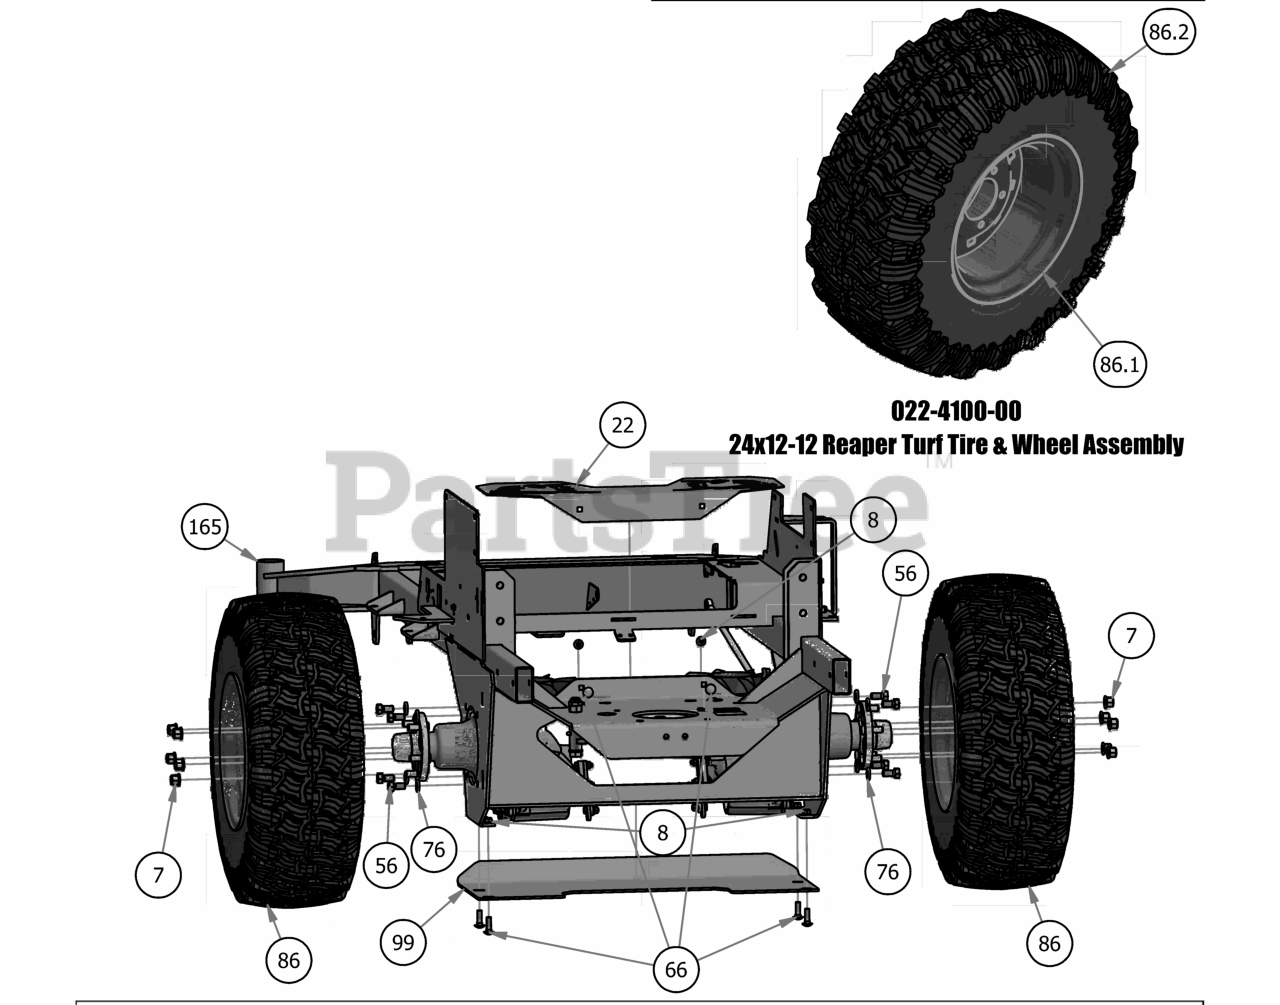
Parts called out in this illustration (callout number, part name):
7	Acorn Lug Nut
8	3/8" Nylock Flange Nut
10	3/8-16 Hex Nuts Zinc
12	1/2" Hex Nut
15	5/16" Nylon Flange Nut
22	2019 Rigid Fan Guard
50	All Thread-Pump Idler Tensioner
51	5/16 x 1 1/4 Hex Bolt
52	5/16" x 1" Bolt
56	1/2" x 1" Hex Bolt
61	1/2" Nylcock Nut (1/2 Jam)
65	3/8" x 1 1/4" Hex Bolt
66	3/8" x 1 1/4" Carriage Bolt
76	1/2" Lock Washer Zinc
77	3/8" Lock Washer
86	24x12-12 Reaper Turf Tire & Wheel Assembly
86.1	12x12" Black Wheel For 2015 Outlaw
86.2	24x12-12 Reaper Turf Tire
99	2019 Outlaw Rigid Skid Plate
125	Deck spring big diameter
126	2019 Outlaw Rigid Push Rod Assembly
127	2015 Outlaw Brake Adapter (4400 Transaxles Only)
129	2019 Rebel Pump Idler
132	2019 Rebel Pump Belt
134.1	Transaxle Spring
134.2	Fan/Pulley Kit for 4400 Transaxle
134.3	Hub/Stud Kit for 4400 Transaxle
134.4	Seal Kit for 4400 Transaxle
134.5	Hydro Filter for 4400 Transaxle
135.1	Transaxle Spring
138	4400 Transaxle - Left Hand
139	4400 Transaxle - Right Hand
139.2	Fan/Pulley Kit for 4400 Transaxle
139.3	Hub/Stud Kit for 4400 Transaxle
139.4	Seal Kit for 4400 Transaxle
139.5	Hydro Filter for 4400 Transaxle
154	Long Brake Cable
165	2019 Rigid Frame
